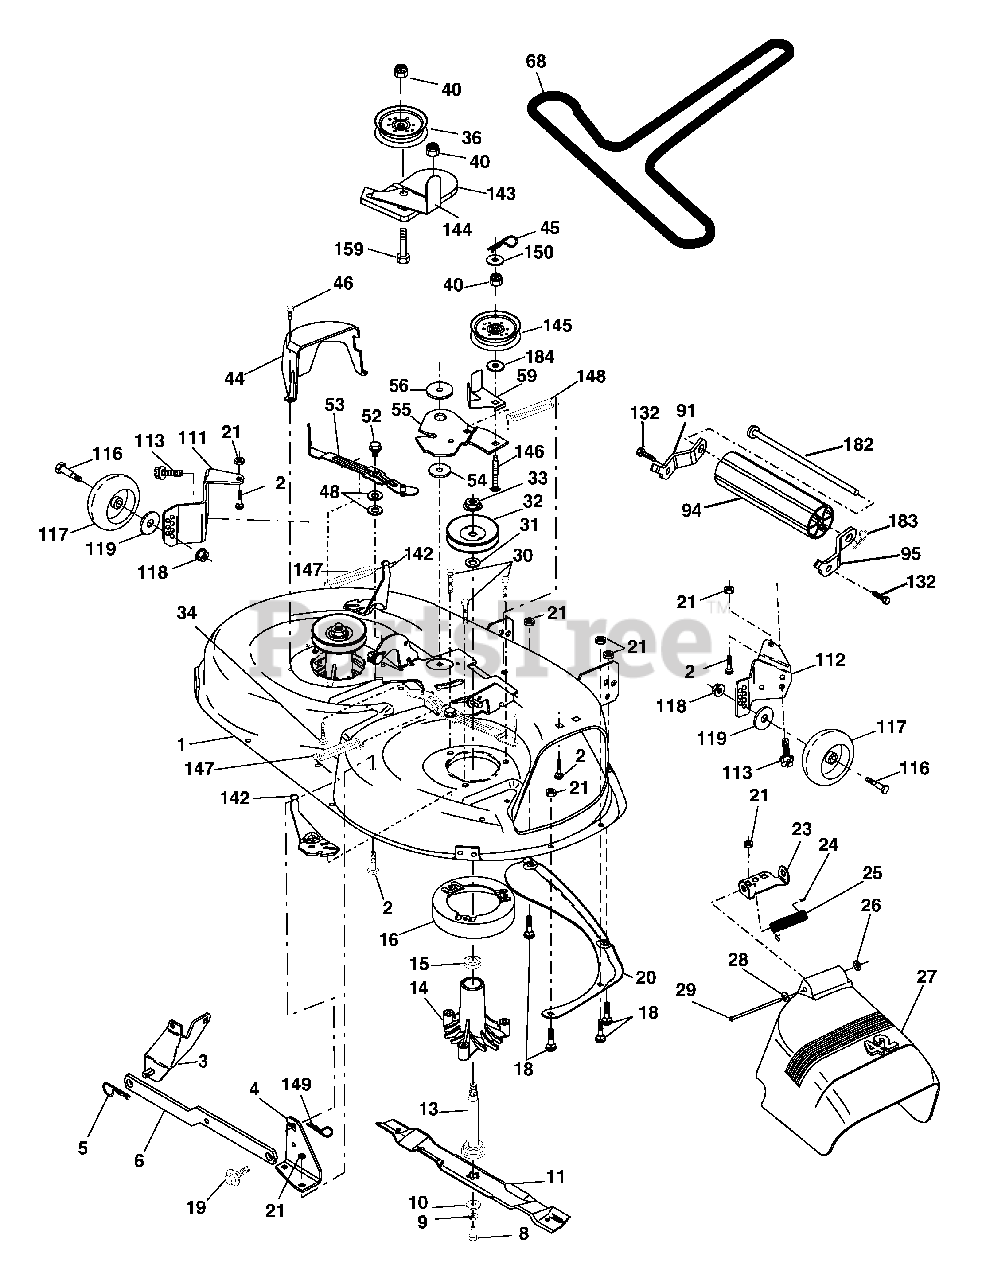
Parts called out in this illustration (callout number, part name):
1	Mower Deck Assembly, 42"
2	Bolt
3	Bracket Asm Fr. Sway Bar 3/42
4	Bracket Asm Deck 42" Sway Bar
5	Retainer Spring
6	Bar Sway Deck
8	Bolt 3/8-24 x 1.25 Gr. 8 patched
9	Washer, Lock
10	Washer, Hardened
11	Blade Mower 42" Hi-Lift
11	Blade, Mulching 42" Std
11	Blade Mulching 42" Premium
13	Shaft Assembly, Mandrel, Vented
14	Housing, Mandrel, Vented
15	Bearing, Ball, Mandrel
16	Stripper, Mandrel Deck
18	Bolt, Carriage 5/16-18 x 5/8
19	Bolt, Shoulder
20	Baffle, Vortex
21	Nut
23	Bracket, Deflector Mower 42"
24	Cap, Sleeve 80 x 112 Blk Mower
25	Spring, Torsion, Deflector 2 52
26	Nut, Push Phos & Oil
27	Shield, Deflector 42" Blk
28	Washer 11/32 x 5/8 x 16 Ga.
29	Rod, Hinge 42" 6 75 W/G
30	Screw Thdrol
31	Washer, Spacer Mower Vented
32	Pulley, Mandrel
33	Nut, Toplock
34	Bolt Carr SH 3/8-16 x 1-1/2 Gr.5
36	Pulley, Idler, Flat
40	Nut Lock 3/8-16
44	Guard, Mandrel, LH
45	Retainer
46	Screw, Thdrol 1/4-20 x 5/8 T
48	Washer, Hardened
52	Bolt, Shoulder 5/16-18 unc
53	Arm Assembly, Pad, Brake
54	Washer, Hardened
55	Arm, Idler
56	Spacer, Retainer
59	Guard TUV Idler
68	V-Belt, 42" Mower
91	Bracket Roller Nose LH
94	Roller Nose
95	Bracket Roller Nose RH
111	Bracket Asm. Whl Ga. LH
112	Bracket Asm Whl Ga. RH
113	Screw 5/16-18
116	Bolt, Shoulder
117	Wheel, Gauge
118	Nut Centerlock 3/8-16
119	Washer 3/8 x 7/8 x 14 Ga.
132	Screw 3/8-16 x 3/4
142	Arm Spring Brake Mower
143	Bracket Arm Idler 42"
144	Keeper Belt 42" Clutch Cable
145	Pulley Idler Flat
146	Bolt Carriage Idler
147	Spring Extension
148	Spring Return Idler
149	Retainer Spring Yellow
150	Washer 9/32 x 3/4 x 10 Ga.
159	Bolt Rdhd Sqn 3/8-16 unc x 1-3/4
182	Rod Roller Nose
183	Retainer Spring
184	Washer 13/32 x 7/8 x 10 Ga.
185	Head Asm Cable Clutch
